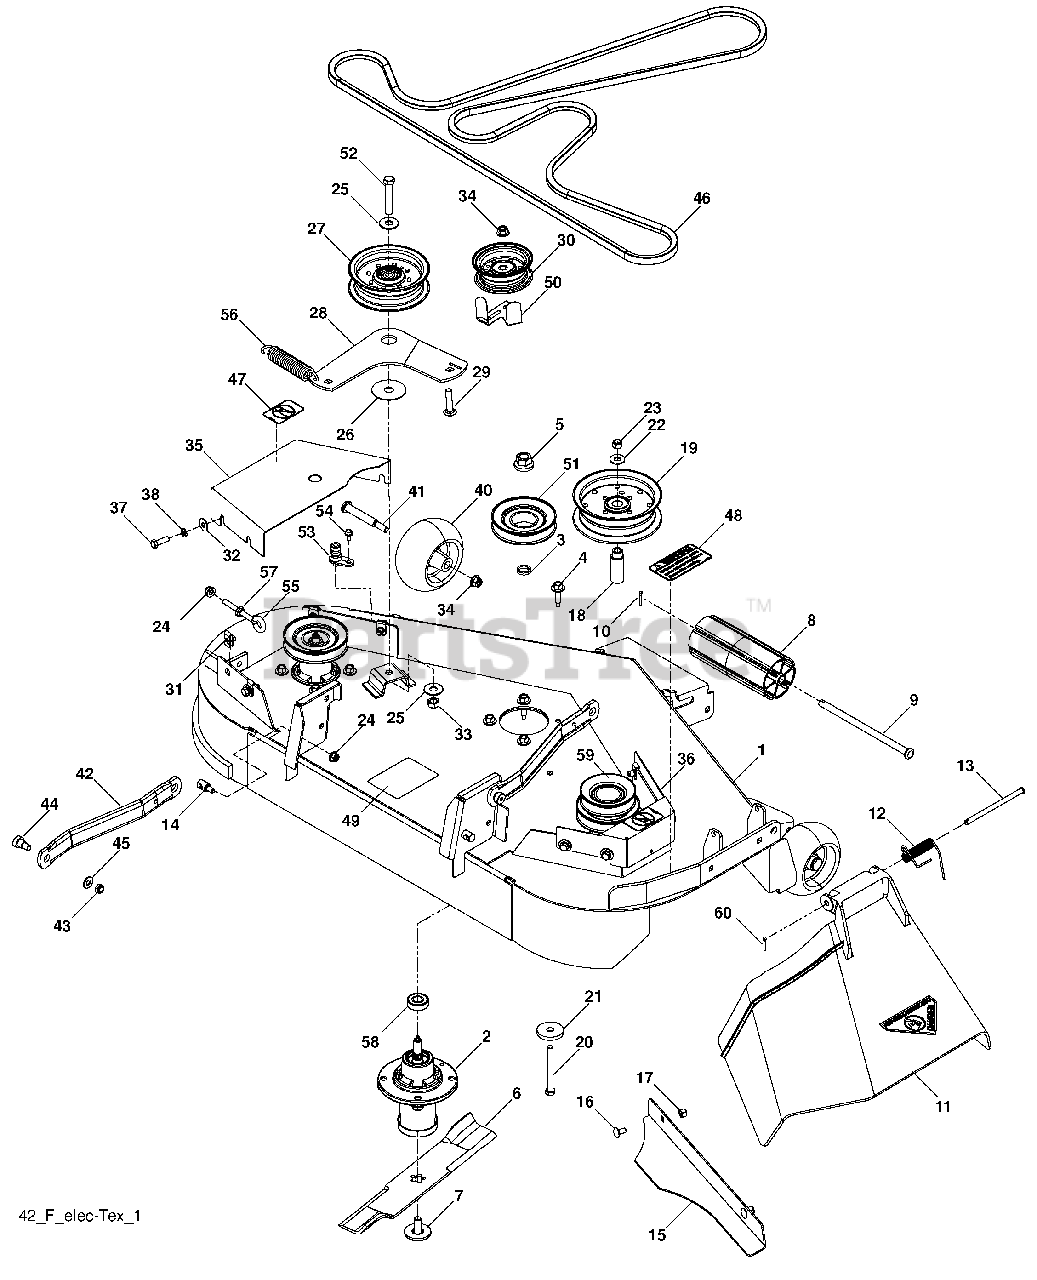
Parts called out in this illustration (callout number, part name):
1	Deck w/Decals 42"
2	Housing Assembly
3	Washer-Spacer
4	Screw, Washer Head
5	Nut, 9/16 Top Center Lock
6	Blade, 14-5/8"
7	Bolt, 7/16, Assy Blade
8	Roller, Nose
9	Rod, Roller, Nose
10	Clip Retainer
11	Discharge Chute - 42" Plastic
12	Spring - Torsion
13	Pin, Clevis 5/16 x 5.19
14	Stud, Fasten w/ Anti- Rotate
15	Confinement Plate
16	Rhsnb 5/16-18 x 5/8 Gr. 5
17	Nut 5/16-18 Hex Nyloc
18	Idler Bushing
19	Pulley, Idler
20	Hcs 3/8-16 x 3-1/2 Gr. 5
21	Heavy Washer
22	Washer, 3/8 Flat Std
23	Nut 3/8-16 Hex Nyloc
24	Nut 5/16-18 Hex Flange Nyloc
25	Washer, 7/16 Flat
26	Washer, Flat Hardened
27	Pulley, Idler Spec. Hub
28	Arm, Idler, Blk
29	Rhsnb 3/8-16 x 1-3/4 Gr. 5
30	Pulley, Idler
31	Retainer 5/16c U Type
32	Washer, 5/16 Std Flt
33	Nut, 7/16-14 Hex Nyloc
34	Nut 3/8-16 Hex Flg Nyloc
35	Shield, Belt LH
36	Shield, Belt RH
37	Hcs 5/16-18 x 1 Gr. 5
38	Wash 5/16 Slw
40	Wheel, Gauge
41	Bolt, Shoulder
42	Arm, Susp., Rear
43	Nut, 3/8-16 Hex Jam Nyloc
44	Sb 3/8-16 x 3/8 Skt Hd
45	Washer, 3/8 Sae Flt
46	Belt, 42" Fab Deck
47	Decal, No Step
48	Decal, Warning
49	Decal, Deck Sch
50	Guard, Belt
51	Pulley, Mandrel
52	Hcs 7/16-14 x 2-1/2 Gr. 5
53	Washout Port
54	Bolt, 1/4-20 x 1/2
55	Eyebolt 5/16 x 3-1/2
57	Nut 5/16-18 Hex Whizlk
58	Ball Bearing
60	Retainter Clip
